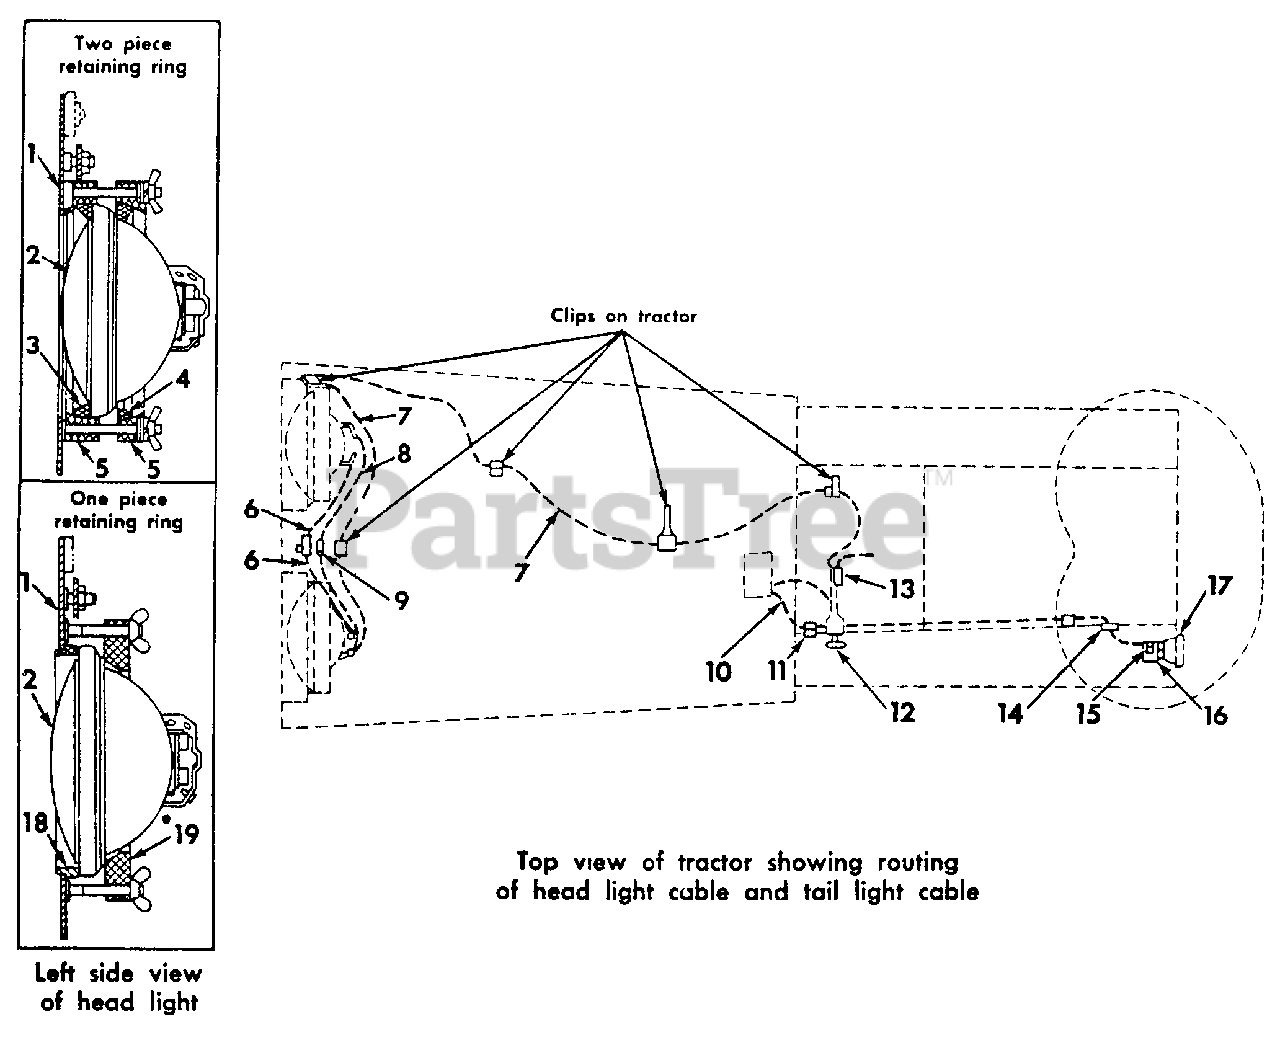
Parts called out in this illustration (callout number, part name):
1	Panel Assy, Headlight Mounting
2	Unit Assy, Headlight Sealed Beam
3	Ring, Headlight Retaining, Front
4	Ring, Headlight Retaining, Rear
5	Ring, Headlight Clamping
6	Cable Assy, Headlight to Ground
7	Cable Assy, Lighting Switch to RH Headlight
8	Cable Assy, RH Headlight to LH Headlight
9	Clip, Headlight Cable
10	Cable Assy, Lighting Switch to Taillight
11	Clip, Taillight Cable
12	Switch Assy, Lighting
13	Cable Assy, Lighting Switch to Key Switch Junction
14	Grommet, Taillight Cable
15	Clip, Taillight Cable
16	Bracket, Taillight Mounting
17	Taillight Assy
18	Ring, Headlight Retaining
19	Ring, Headlight Clamping
